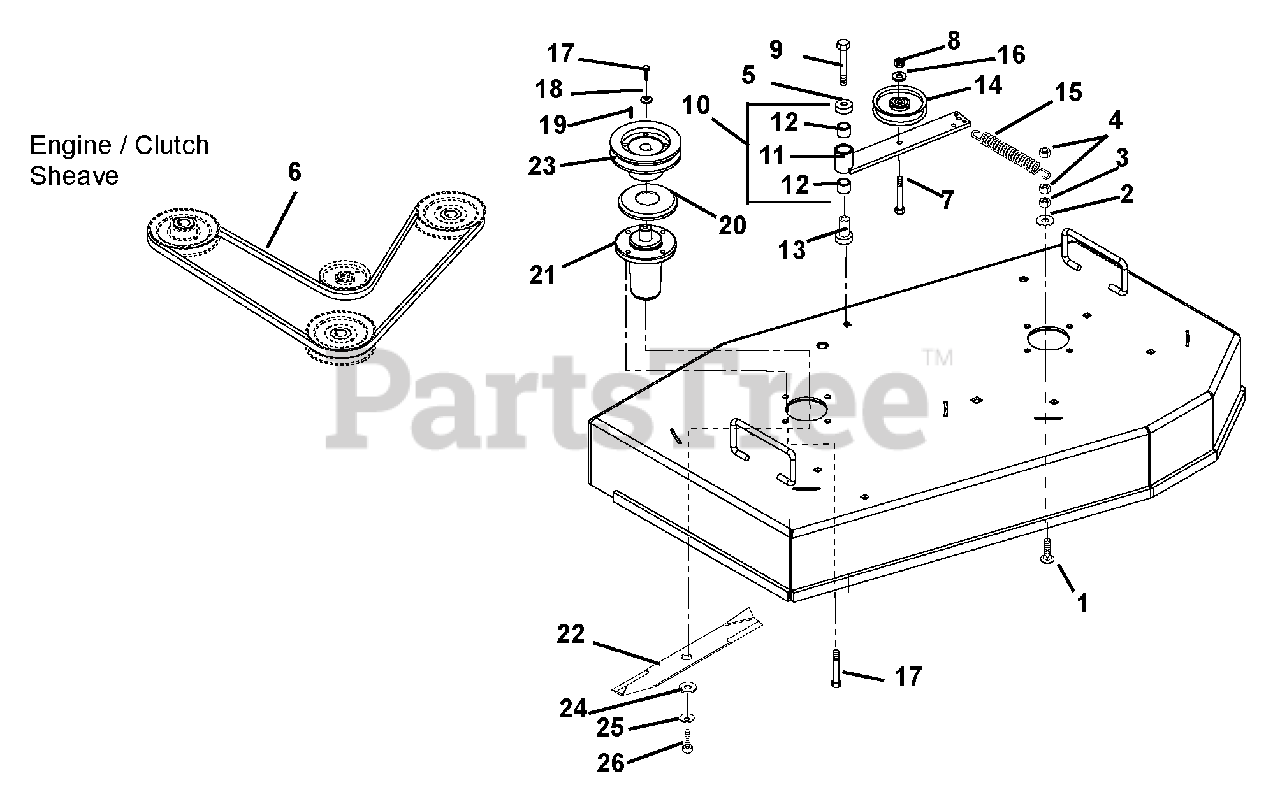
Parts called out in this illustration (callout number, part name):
1	@BLT-RDHDSQNK .38-16X1.50 G5YZ
2	@WSHR-LK .38X.094 REG YWZC
3	@NUT-HEX .38-16 YWZC
4	@NUT-LK-CTR .38-16 YWZC
5	WSHR-FL-STL .515X1.625X.250 YZ
6	V-BELT, HB-WRAPPED
7	@BLT-RDHDSQNK .38-16X3.00 G5YZ
8	@NUT-LK-CTR .38-16 YWZC
9	@BLT-HEX .50-13X3.75 GR5 YWZC
10	ASSEMBLY - IDLER PIVOT ARM
11	WMT - IDLER PIVOT ARM
12	BRG, 1.00 X 1.12 X .75
13	BEARING, PEDESTAL
14	IDLER-FLAT 4.00X.38 (2.00 W)
15	SPRING, EXTENSION
16	SEAL, IDLER BEARING
17	BLT-HEX .38-16X1.00 YZ GR8
18	WSHR,FLT STL.406X1.50X.245YWZC
19	KEY, SQ .25X.25X1.00 RC 40-50
20	SLINGER, DUST
21	ASM,MAINT FREE SPINDLE
22	BLADE, 32" (16.25)
22	BLADE, 36" SAND, TUNGSTEN
23	WELDMENT, SPINDLE SHEAVE 5.00
24	WSHR-FLT .640X1.75X.250 YWZC
25	WSHR-BLVL .669X1.535X.138
26	BLT-HEX .62-18X1.75 GR8 YWZC
